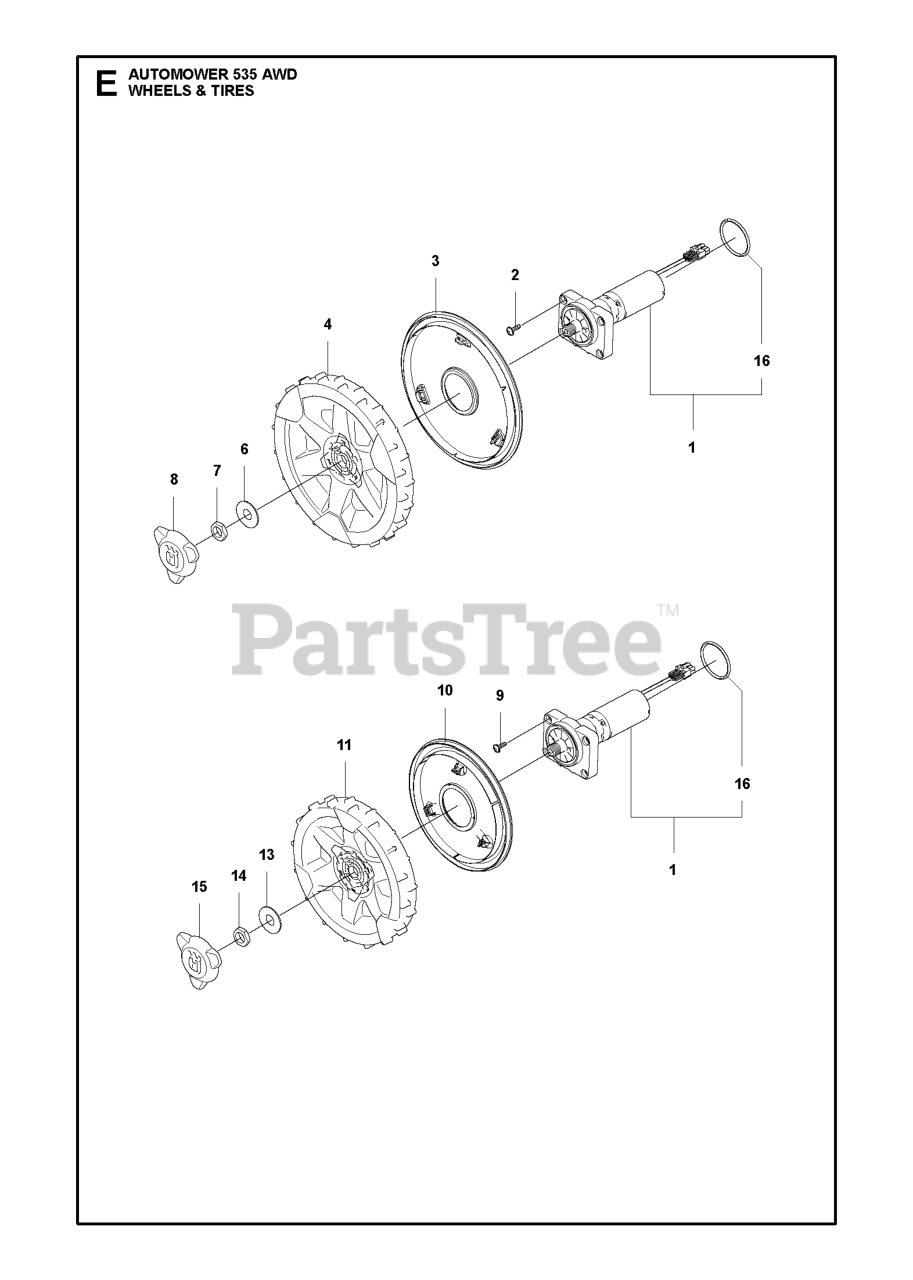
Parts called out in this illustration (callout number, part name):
1	CLG
2	SCREW ITXPANT
3	COVER REAR WHEEL
4	Wheels
6	WASHER WASHER REAR WHEEL 16X40
7	HEXAGON THIN NUT
8	HUB CAP REAR WHEEL NO CENTER P
9	SCREW ITXPANT
10	COVER REAR WHEEL
11	WHEEL COVER GREY HVA
13	WASHER WASHER REAR WHEEL 16X40
14	HEXAGON THIN NUT
15	HUB CAP REAR WHEEL NO CENTER P
16	O-RING LIGHT GREY
